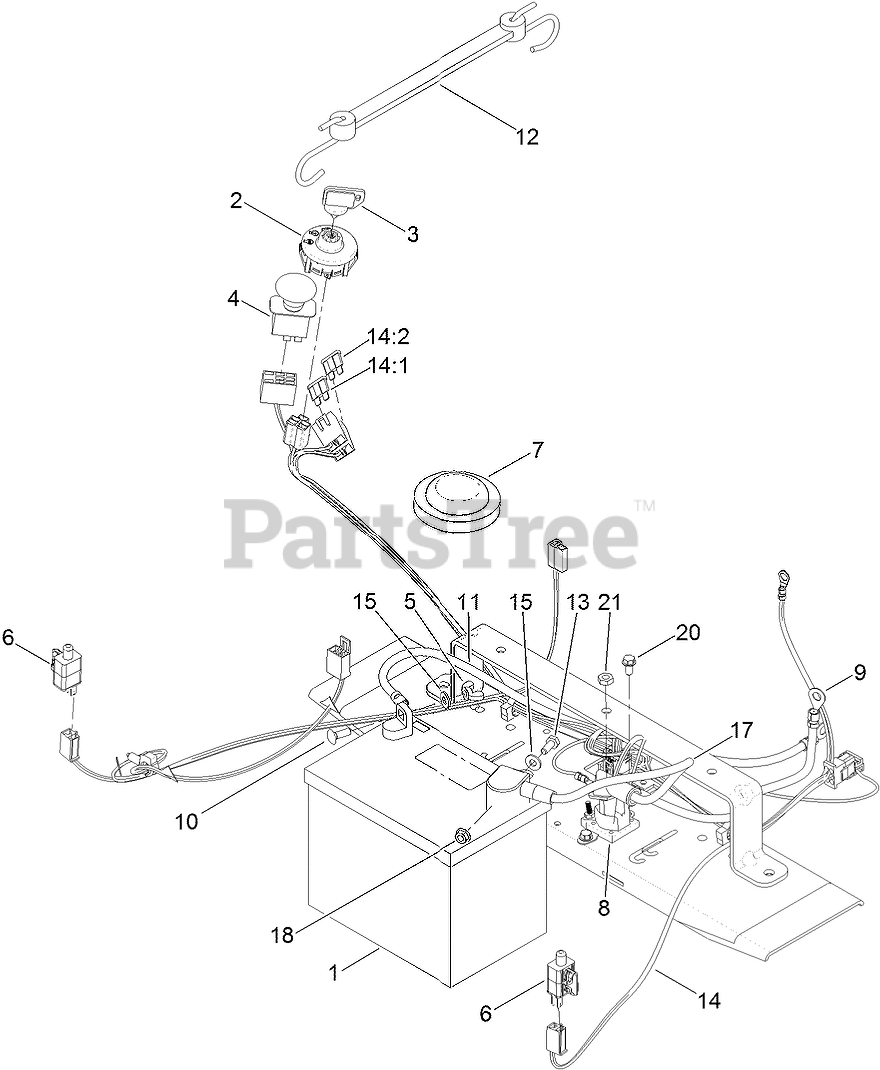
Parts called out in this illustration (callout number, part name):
1	BATTERY
2	SWITCH-IGNITION
3	KEY-IGNITION
4	SWITCH-PTO
5	NUT-WING
6	SWITCH
7	SWITCH-SEAT
8	SOLENOID
9	CABLE-BATTERY, RED
10	BOLT-CARR
11	CABLE-BATTERY, BLACK
12	HOLDDOWN-BATTERY
13	SCREW-HH
14	HARNESS-WIRE
14:1	FUSE-BLADE, 30 AMP
14:2	FUSE-BLADE, 25 AMP
15	WASHER-FLAT
17	CABLE-BATTERY, RED
18	NUT-HF
20	SCREW-HWH
21	NUT-JAM
